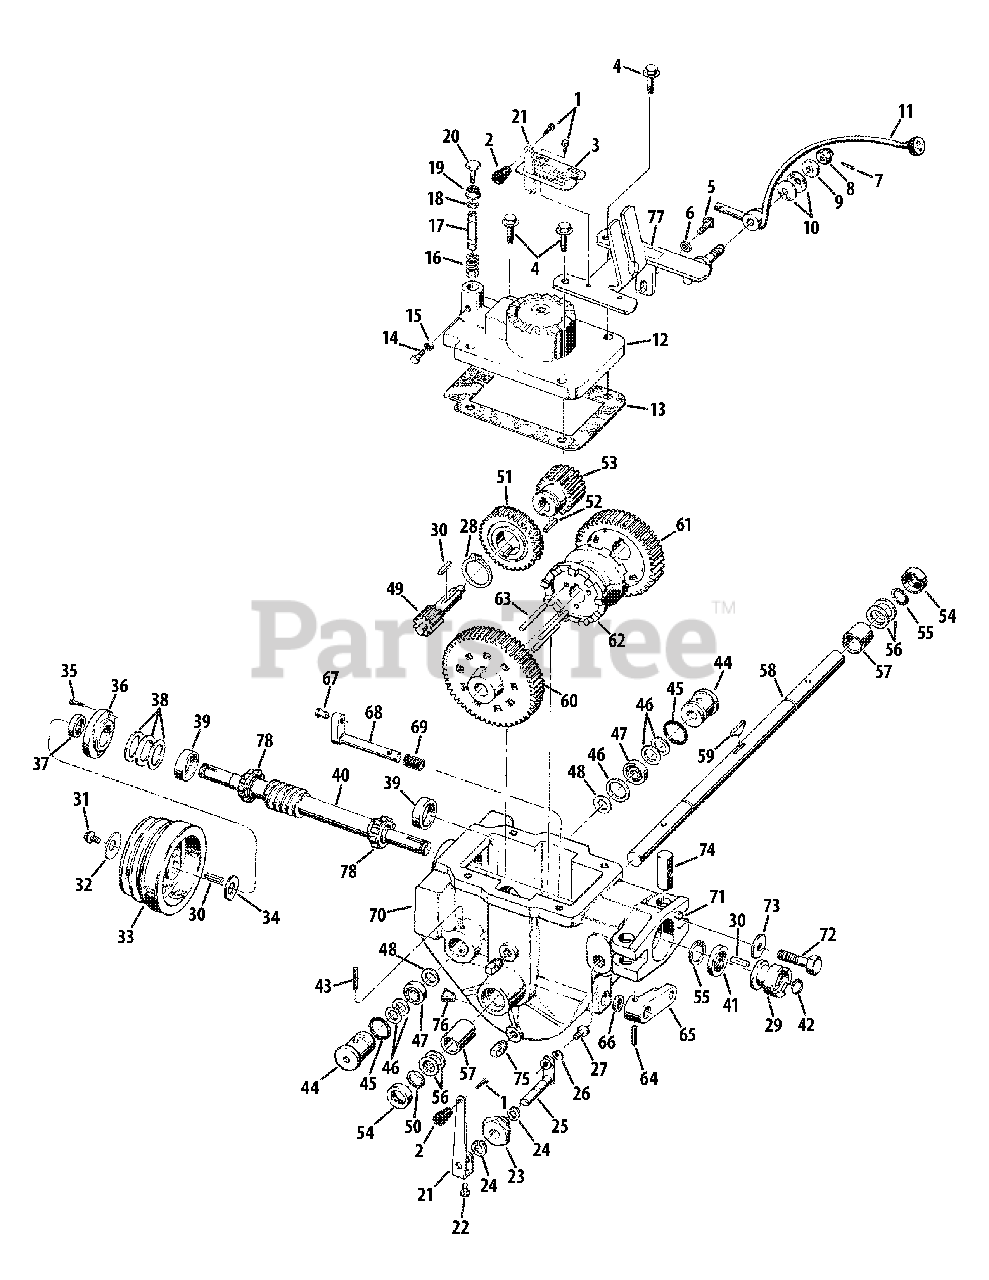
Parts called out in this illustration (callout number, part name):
1	Hex Head Screw, #10-32 x 3/8"
4	Hex Flange Bolt, 3/8"-16 x 1-1/2"
5	Hex Flange Bolt, 5/16"-18 x 3/4"
6	Flat Washer, 5/16"
7	Spring Pin, 1/8"
8	Hex Nut, 1/2"-20
9	Shoulder Washer, 1.25 x .50 x .25
10	Disc Spring Washer, 1.97 x 1.0 x .118
11	Wheel Speed Shift Lever
12	Power Unit Transmission Cover
13	Transmission Cover Gasket
14	Hex Head Screw, 5/16"-18 x 1"
15	Hex Nut, 5/16"-18
16	Plunger Spring
18	Clip Ring
19	Flange Lock Nut, 3/8"-16
20	Screw, 3/8"-16 x 1-1/2"
21	Tines/PTO Clutch Lever
22	Hex Head Screw, 1/4"-20 x 1/2"
23	Tines/PTO Clutch Bushing
24	External Retaining Ring
25	Tines/PTO Clutch Shaft
26	Hi-Collar Lockwasher, 1/4"
27	Socket Head Screw, 1/4"-20 x 3/8"
28	External Retaining Ring
29	Dog Clutch
30	Key, 3/16" x 1"
31	Hex Head Screw, 5/16"-24 x 3/4"
32	Spring Washer, .827 x .331 x .098
33	Transmission Drive Pulley
34	Flat Washer, 1.25 x .687 x .075
35	Flange Nut, 1/4"-20 x .75
36	Front Bearing Cap
38	Flat Washer, 1.175 x 1.5 x .062
38	Flat Washer, 1.175 x 1.5 x .005
38	Flat Washer, 1.175 x 1.5 x .03
38	Flat Washer, 1.175 x 1.5 x .01
39	Cup Bearing
40	Main Drive Shaft
42	Retaining Ring
43	Roll Pin (Spirol), 1/4" x 2
44	Pinion Bearing
46	Flat Washer, 1.234 x 1.015 x .062
46	Flat Washer, 1.234 x 1.015 x .033
46	Flat Washer, 1.234 x 1.015 x .01
47	Ball Bearing
48	Washer
49	Pinion Stem
50	External Retaining Ring, 1.387 ID
51	Worm Gear
52	Key, 3/16" x 5/8"
53	Fast Speed Pinion Gear
55	External Retaining Ring
56	Flat Washer, 1.375 x 1.015 x .005
56	Flat Washer, 1.375 x 1.015 x .01
56	Flat Washer, 1.375 x 1.015 x .015
56	Flat Washer, 1.375 x 1.015 x .03
56	Flat Washer, 1.375 x 1.015 x .062
57	Bushing, 1.25 x 1.005 x 1.5
58	Wheel Shaft Asm
59	Hi-Pro Key, .250 x 1.8125
60	Slow Speed Gear
61	Faste Gear Speed
62	Dog Clutch
63	Clutch Guide Pin, 1/4"
64	Spring Pin, 3/16" x 1-1/4"
65	Wheel Speed Shifting Lever
67	Wheel Speed Shifting Pin
68	Wheel Speed Shifting Shaft
70	Transmission Housing
71	Alignment Pin
72	Hex Screw, 1/2"-13 x 2"
73	Disc Spring Washer
75	Pipe Plug, 1/4"
76	Plug-Red Plastic
77	Clutch Bracket
78	Cone Bearing
